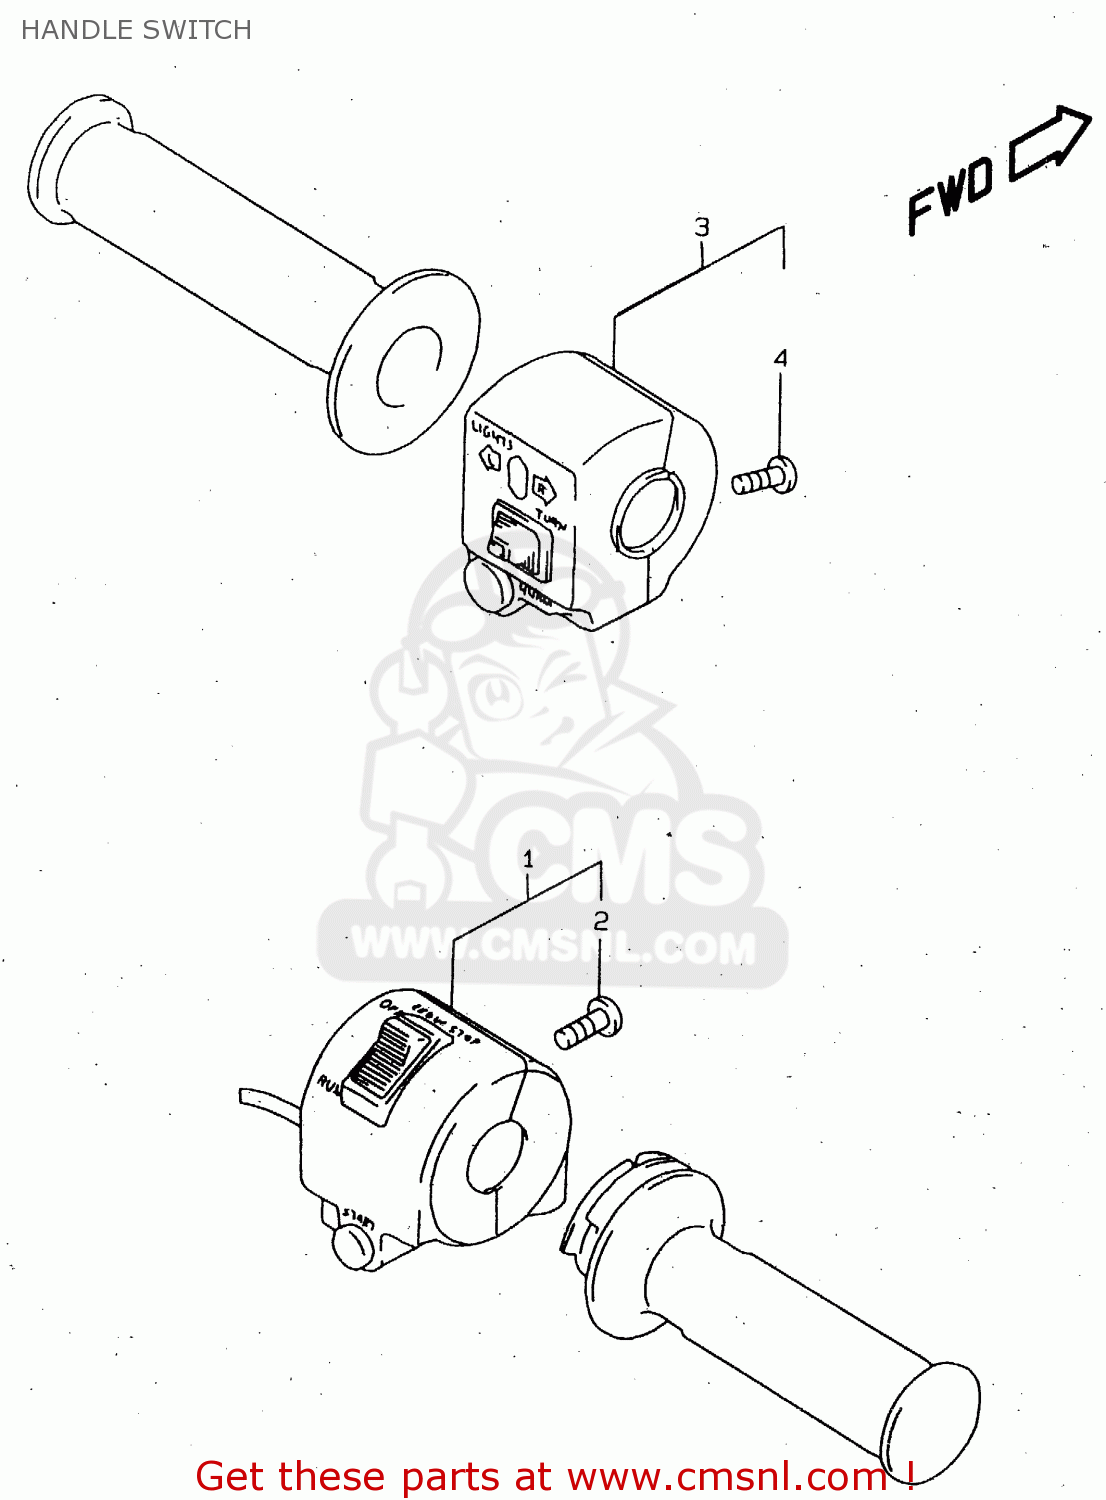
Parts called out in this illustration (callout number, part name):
1	SWITCH ASSY,HANDLE,R
2	SCREW(5X14)
3	SWITCH ASSY,HANDLE,L
4	SCREW
